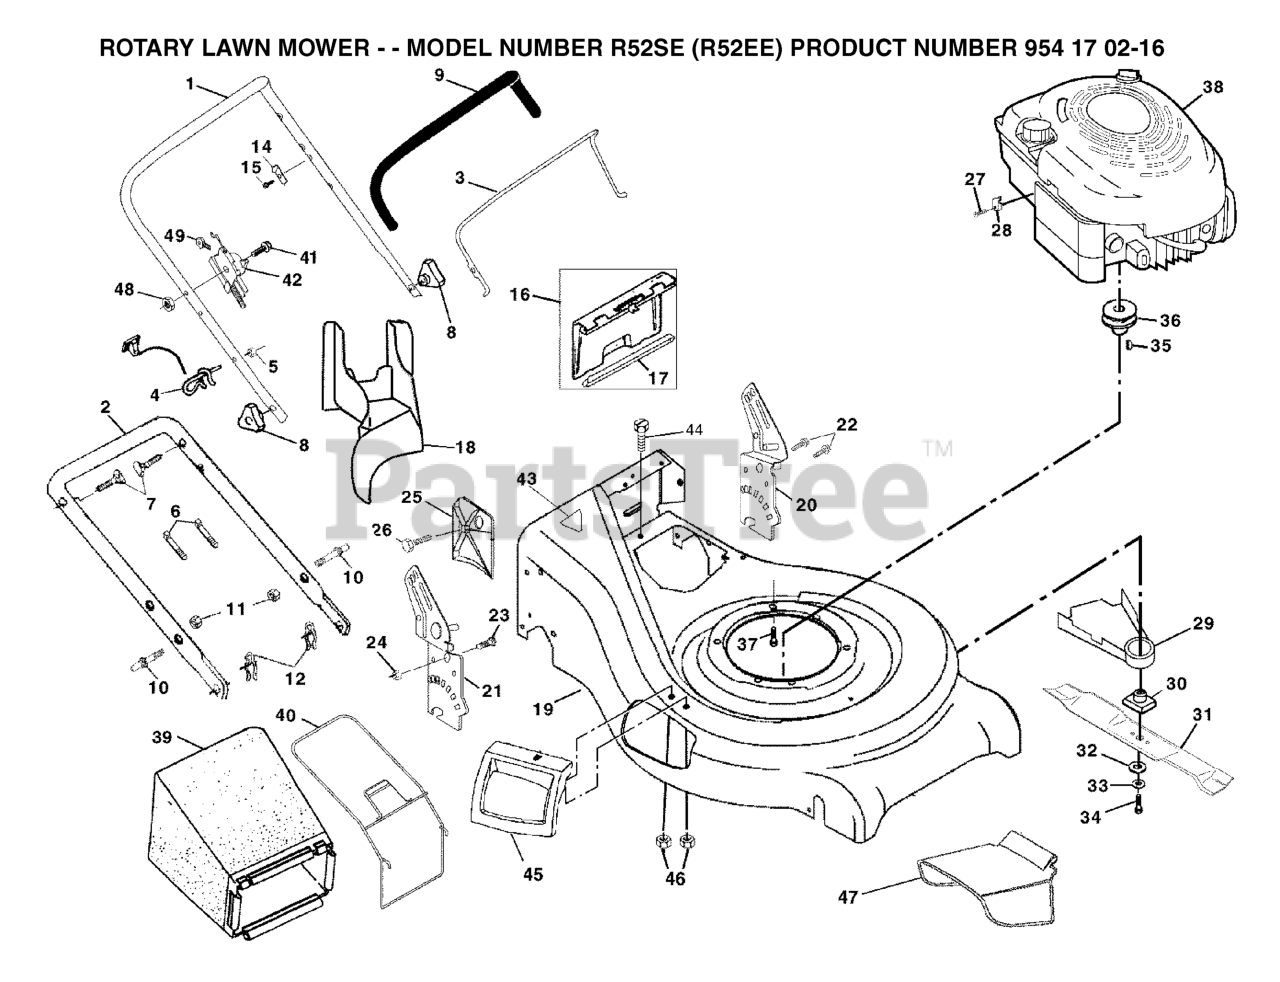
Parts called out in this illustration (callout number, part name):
1	HANDLE.UP.DLX.COMF.W/GRIP.GREY
2	HANDLE
3	CONTROL BAR
4	ROPE, GUIDE
5	NUT
6	TIE GUIDE
7	HANDLE BOLT
9	GRIP.HANDLE.FOAM
10	BOLT
11	NUT
12	HAIRPIN COTTER
14	BRACKET UPSTOP
16	KIT.DOOR.REAR.21.WRAPPED.BLACK
17	SEAL.DOOR.21" (2 2MC)
18	PLUG, MULCHER
20	.RACKET
21	RIGHT HANDLE BRKT. ASSM.
22	SELF-TAPPING SCREW 5/16-18X3/4
23	BOLT, HEX HEAD 5/16-18
24	NUT.71038.31-18.HEX.NYLOCK
25	CLIPPING DEFLECTOR
27	SCREW.HEX.HEAD.WASHER.10-16
28	CABLE CLAMP(ENGINE)
29	SHIELD.DEBRIS.21.RWGD.EZ
30	BLADE ADAPTER
32	WASHER,HARDEN
33	LOCKWASHER
34	SCREW, HEX HD 3/8-24 X 1-3/8
35	HI-PRO KEY
36	PULLEY.ENG.25MMM
37	BOLT 3/8-16X1-1/8
40	FRAME.GRASS.CATCHER.21.RGD
42	CONTROL.ELECTRIC.KEY.START
43	DECAL.INTERNATIONL.CUTFINGER
45	MULCHER DOOR ASM.
47	DEFLECTOR, DISCHARGE
48	LOCK NUT
49	KEY.MOLDED.GENERIC
